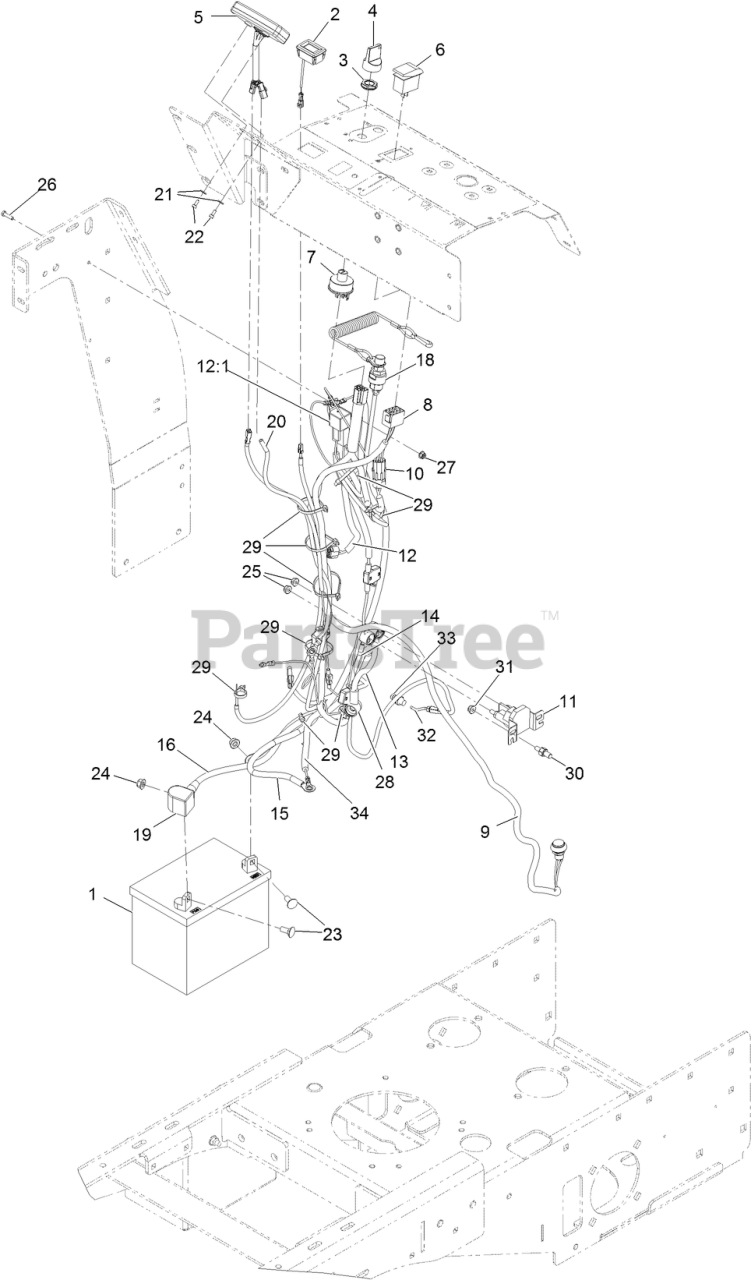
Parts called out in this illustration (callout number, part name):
1	BATTERY (340 CCA, WET)
2	METER-TACH/HOUR
3	NUT-SWITCH, KEY
4	KEYS-IGNITION (SPARE PAIR)
4	KEY-UMBRELLA
5	STRIKER-HEAD ONLY
6	SWITCH-ROCKER
7	SWITCH-IGNITION
8	CONNECTOR-CARLING, 8F
9	SWITCH-PUSH BUTTON
10	CONNECTOR-WP,2M
11	SOLENOID-STARTER
12	HARNESS-MAIN
12:1	RELAY-MINI ISO PWR, 5M
13	CABLE-BATTERY, POSITIVE
14	WIRE-SOLENOID
15	CABLE-GROUND
16	CABLE-POSITIVE
18	SWITCH-OP
19	INSULATOR-BATTERY
20	HARNESS-STRIKER
21	WASHER-FLAT
22	SCREW-HSH
23	SCREW-CARR
24	NUT-HEX FLANGE
25	NUT-HF
26	SCREW-HH
27	NUT-HEX FLANGE
28	INSULATOR-SOLENOID
29	TIE-CABLE
30	STUD-ENGINE
31	NUT-HEX FLANGE
32	CABLE-SENSOR, TRAIL TECH
33	MAGNET-SPEEDOMETER
34	HARNESS-WIRE, JUMPER
